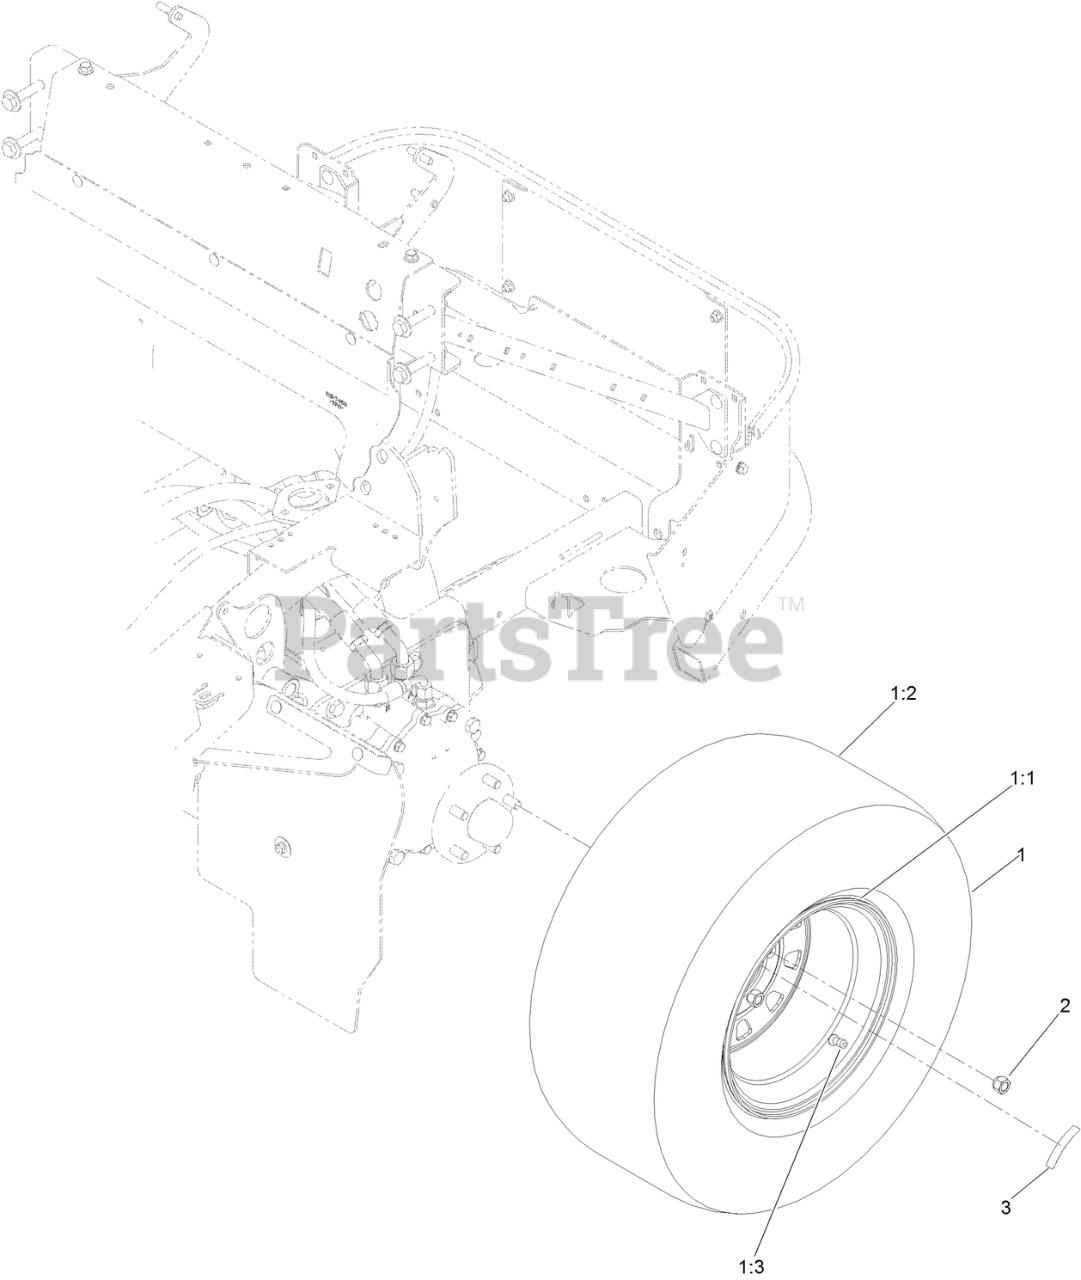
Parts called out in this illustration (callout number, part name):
1	TIRE ASM
2	NUT-LUG
3	DECAL-TORQUE, WHEEL NUT
